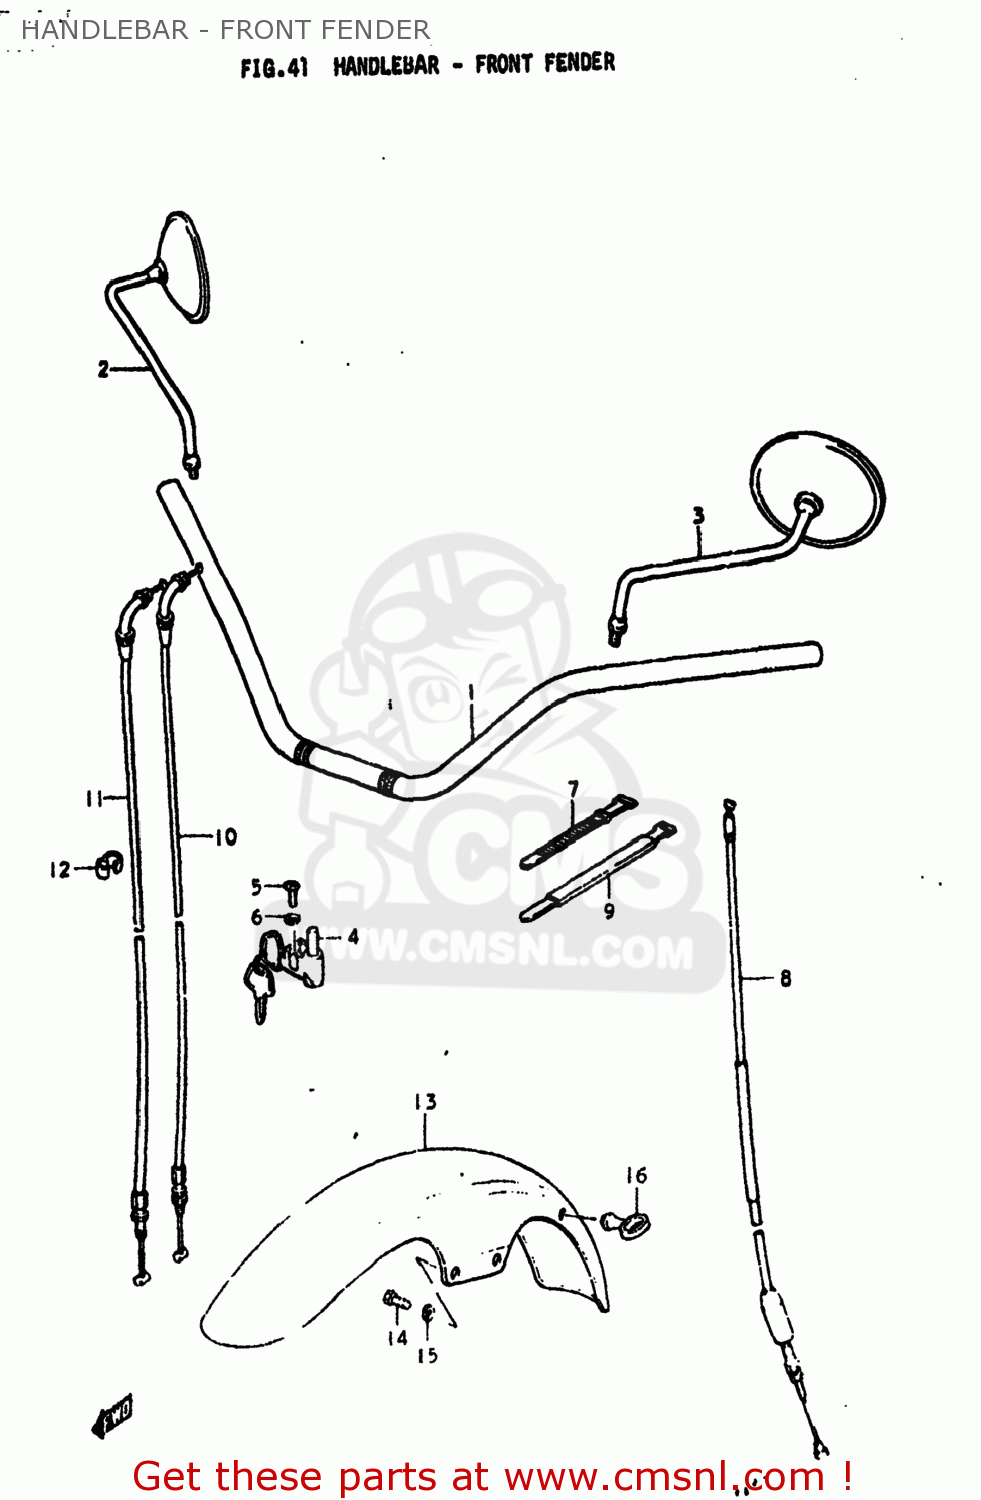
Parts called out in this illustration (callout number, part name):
1	HANDLEBAR
2	MIRROR ASSEMBLY,RIGHT
3	MIRROR ASSEMBLY,LEFT
4	LOCK ASSEMBLY,STEERING
5	SCREW
6	LOCK WASHER
7	CLAMP(L:120)
8	CABLE ASSEMBLY,CLUTCH
9	CLAMP
10	CABLE ASSEMBLY,THROTTLE
11	CABLE ASSEMBLY,THROTTLE
12	CLIP
13	FENDER,FR
14	BOLT
15	LOCK WASHER
16	GUIDE,CABLE
